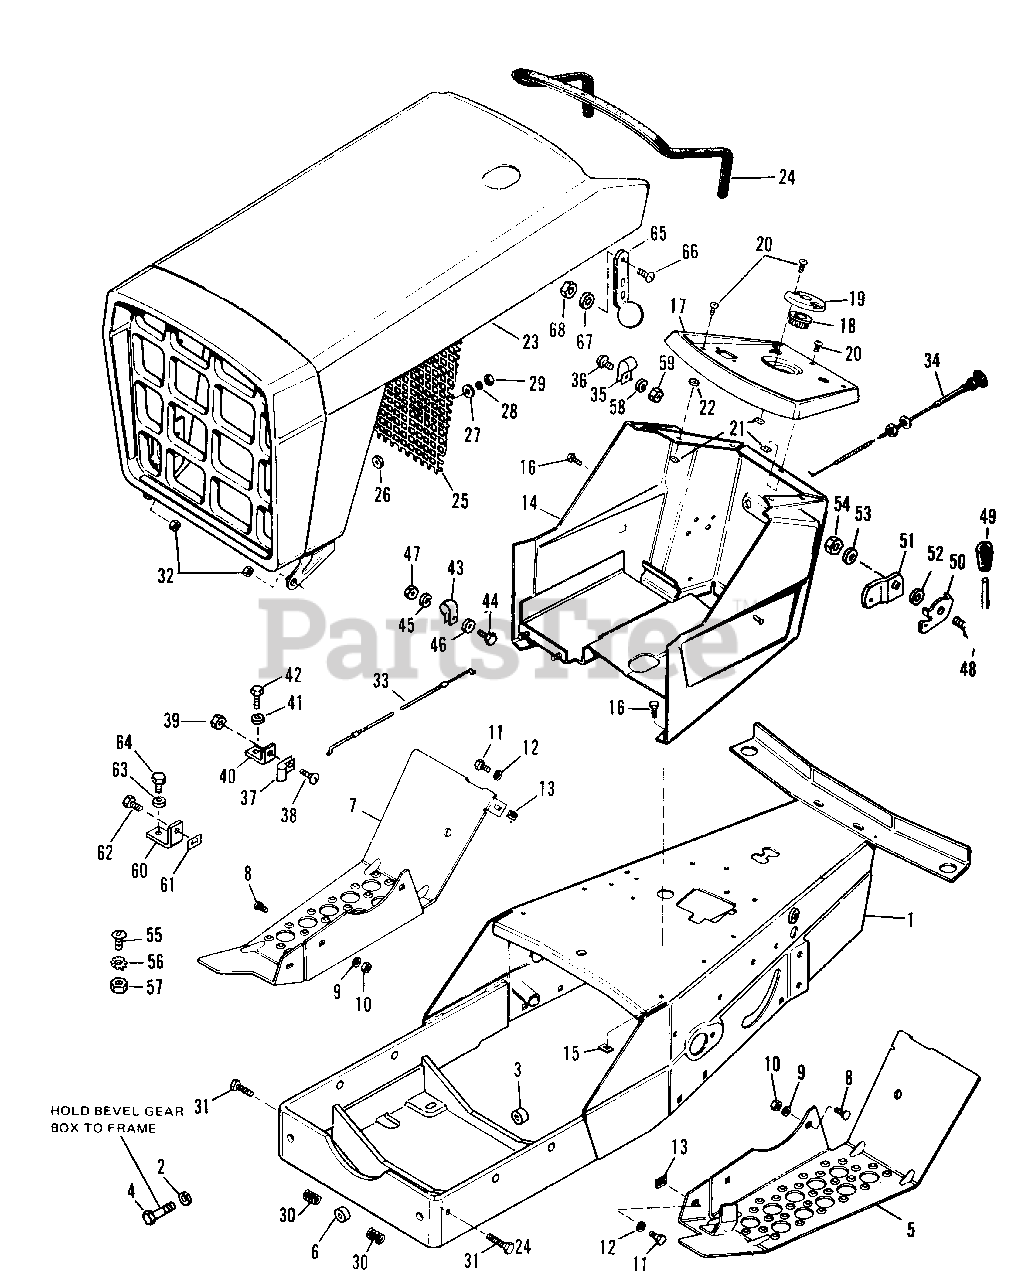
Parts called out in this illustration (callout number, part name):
1	Frame Assy.
2	Lock Washer, 7/16"
4	Hex Cap Screw, 7/16"-14 N.C. x 1-1/2"
5	Foot Rest R.H.
7	Foot Rest L.H.
8	Carriage, Bolt, 5/ 16 "-16 N.C. x 3/4"
9	Lock Washer, 5/16"
10	Hex Nut, Full, 5/16"-18 N.C.
11	Hex Cap Screw, 5/16"-18 N.C. x 3/4"
12	Lock Washer, 5/16"
13	Nut, Tinnerman, 5/16"-18 N.C.
14	Dash Assembly
15	Nut, Tinnerman
16	Hex Head Self Tapping Screw, No. 14 AB x 3/4"
17	Panel, Instrument
18	Bushing, Steering
19	Plate, Steering Adj.
20	Round Head Phillips Screw, 1/4"-20 N.C. x 1/2"
21	Nut, Tinnerman, 1/4"-20 N.C.
22	Plain Washer
23	Grille & Hood Assy.
24	Molding, Hood
25	Screen, Grille
28	Lock Washer, Shakeproof No. 10
29	Nut, Hex Full, No. 10-24 N.F.
31	Hex Cap Screw, 3/8"-16 N.C. x 1-1/2"
32	Hex Lock Nut, Center, 3/8"-16 N.C.
33	Throttle Control
34	Choke Control
35	Clip, Bowden Wire
36	Self Tapping Rd. Hd. Screw, No. 10-24 N.C. x 1/2"
37	Clip, Bowden Wire
38	Rd. Hd. Mach. Screw, No. 10-32 N.F. x 3/8"
39	Full Hex Nut, No. 10-32 N.F.
40	Bracket, Throttle Cable
41	Lock Washer, 1/4"
42	Self Tapping Rec. Hex Hd. Screw, 1/4"-20 N.C. x 5/8"
44	Hex Cap Screw, 1/4"-20 N.C. x 5/8"
45	Lock Washer, 1/4"
46	Plain Washer, 1/4" Std.
47	Hex Nut Full, 1/4"-20 N.C.
48	Throttle Handle
49	Knob
50	Stop Throttle
51	Arm Throttle
53	Washer Lock Dished Type, 3/8"
54	Full Lock Hex Nut, 3/8"-6 N.C.
55	Truss Hd. Screw, No. 10-32 x 1/2"
57	Gripco Lock Nut 10-32 x 1/2"
58	Lock Washer, No. 12
59	Hex Nut Full, No. 10-24
60	Bracket, Pulley Guard
61	Nut, Tinnerman
62	Hex Cap Screw, 1/4"-20 x 3/4"
63	Plain Washer, 3/16"
64	Hex Hd. Screw, No. 14 x 1-1/4"
66	Rd. Hd. Mach. Screw, No. 10-32x 1/2"
67	Lock Washer, Shakeproof No. 10
68	Nut, Hex Full, No. 10-32
